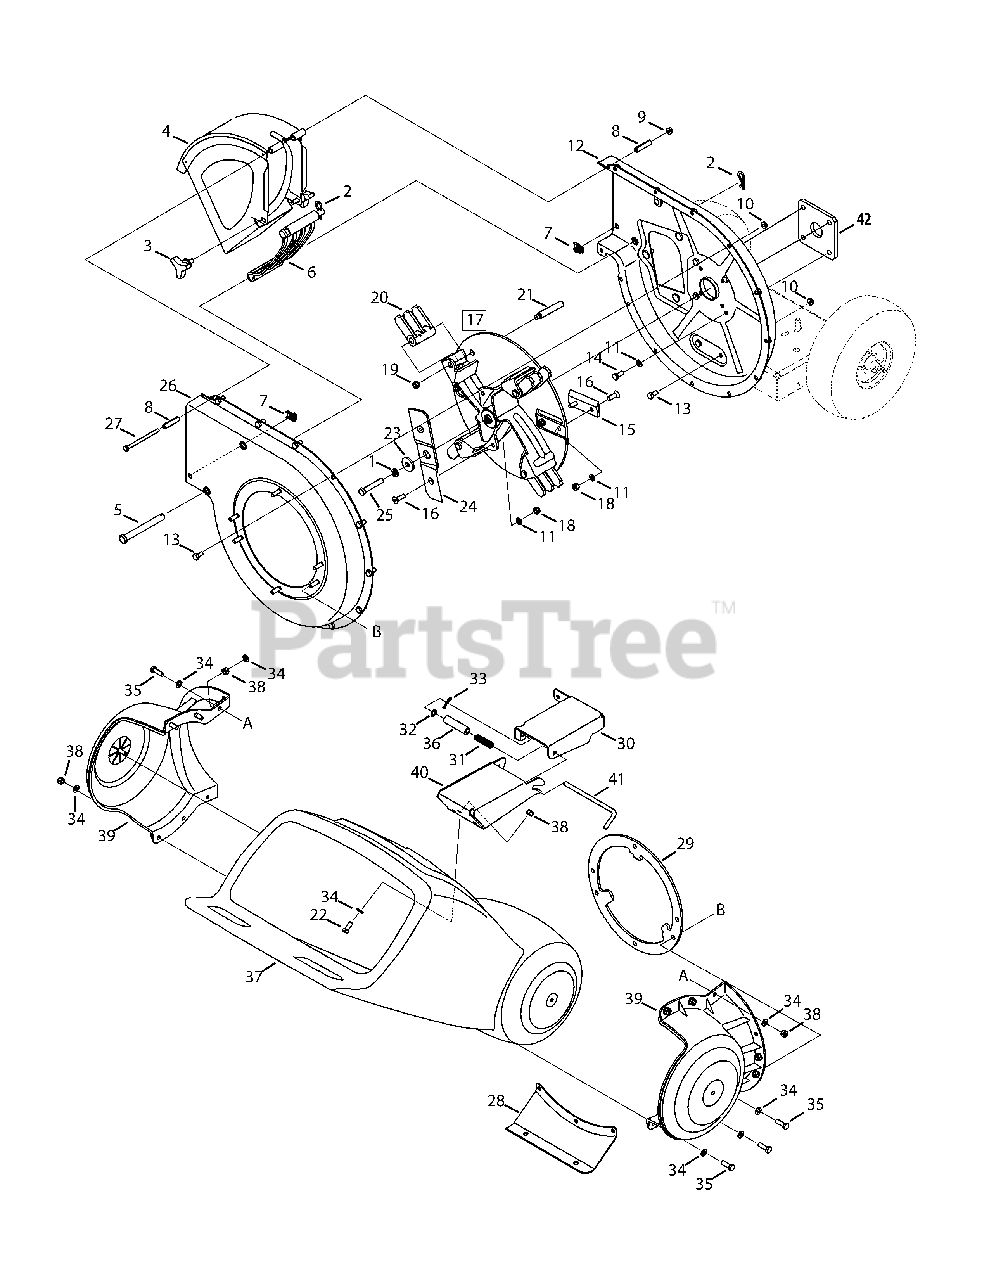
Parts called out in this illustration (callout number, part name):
1	Lock Washer, 3/8
2	Cotter Pin
3	Wing Knob 5/16-18
4	Chute Deflector Assembly
5	Clevis Pin
6	Shredder Screen
7	U-Nut 5/16-18
8	Spacer
9	Hex Lock Nut, 1/4-20
10	Hex Lock Nut 5/16-18
11	Lock Washer 5/16
12	Inner Impeller Housing Assembly
13	Hex Cap Screw 5/16-18 x .625
14	Hex Cap Screw 5/16-24 x 1.00
15	Chipper Blade (standard)
15	Chipper Blade (premium)
16	Hex Cap Screw 5/16-24 x 1.0
17	Impeller Assembly (standard)
17	Impeller Assembly (premium)
18	Hex Lock Nut 5/16-24
19	Nut, Jam Lock, 3/8-16
20	Flail Blade
21	Shoulder Pin, .5 x 2.625
22	Hex Cap Screw 5/16-18 x .75
23	Flat Washer 3/8 x 1.25
24	Shredder Blade
25	Hex Cap Screw 3/8-24 x 2.25
26	Outer Impeller Housing Assembly
27	Hex Cap Screw 1/4-20 x 3.75
28	Front Support Bracket
29	Shredder Plate
30	Rear Hopper Bracket Assembly
31	Compression Spring 1.75
32	Flat Washer
33	Cotter Pin
34	Flat Washer .330 ID x. 630 OD
35	Hex Cap Screw 5/16-18 x 1.0
36	Spacer,.375 ID x 2.50 LG
37	Hopper Assembly
38	Hex Lock Nut 5/16-18
39	Hopper Collar
40	Front Hopper Bracket Assembly
41	Lock Rod
42	Engine Plate
